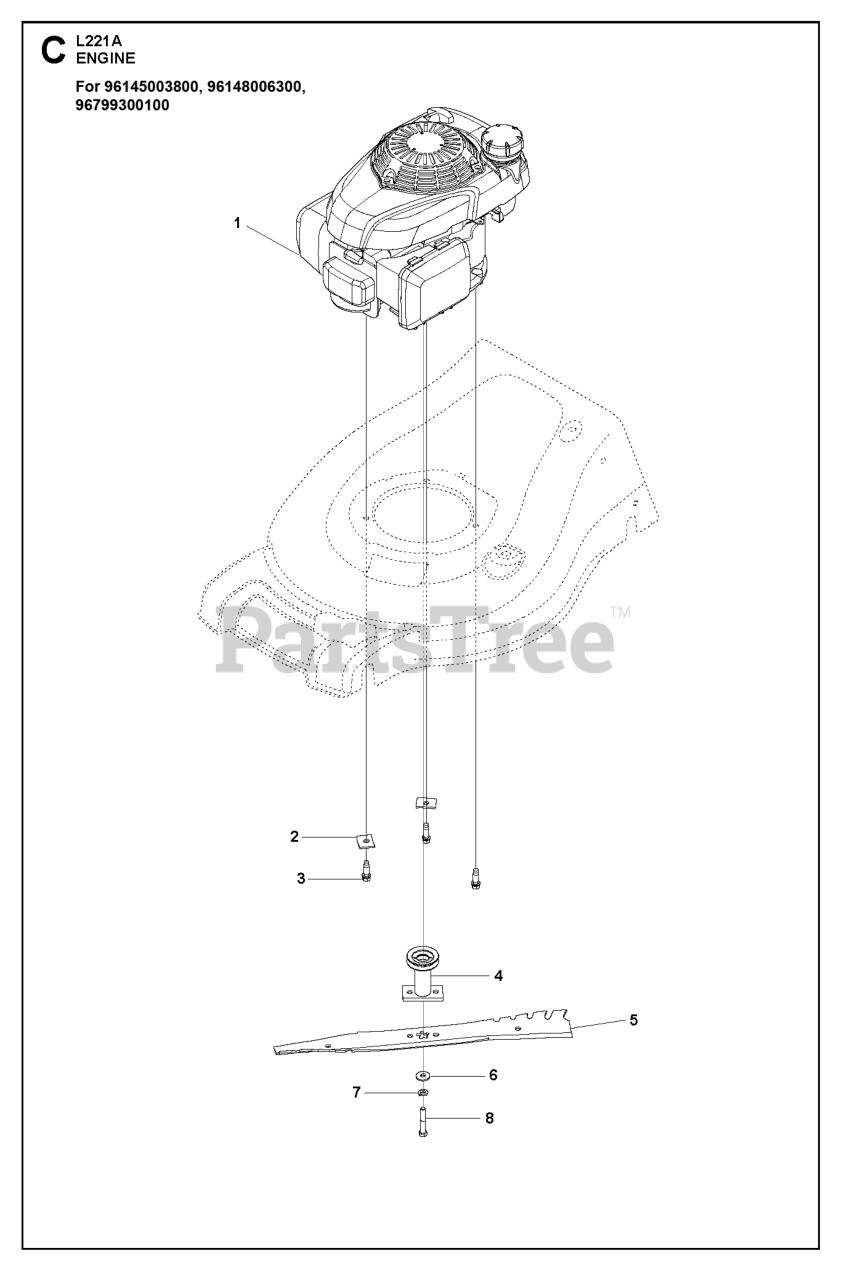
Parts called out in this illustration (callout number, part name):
2	WASHER.ENGINE.BZP
3	BOLT 3/8-16X1-1/8
4	ADAPTER.BLD.25M.2P.AW/RW/21EFF
5	BLADE.21.REAPER.WO/NOTCHES
6	WASHER,HARDEN
7	LOCKWASHER
8	BOLT.ENGINE.PULLEY
